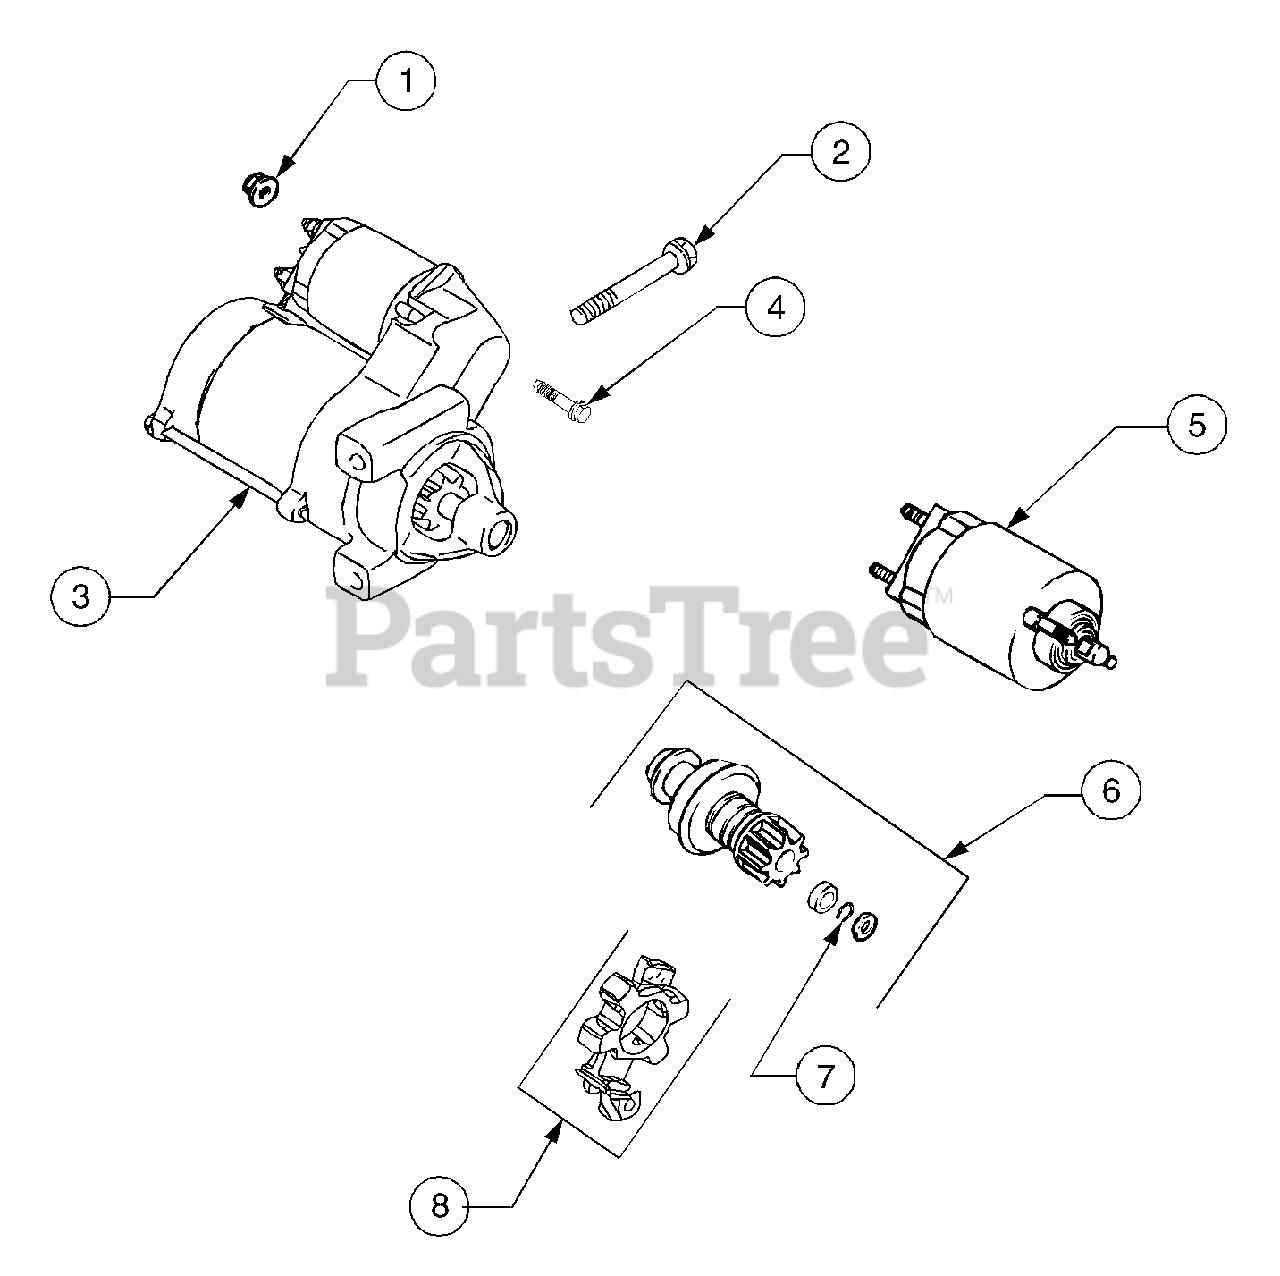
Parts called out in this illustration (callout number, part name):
1	Nut, Hex Flange M8 x 1.25"
2	Screw, Hex Flange M8 x 1.25 x 80
3	Starter, Solenoid Shift Assembly
4	Kit, Solenoid
5	Kit, Pinion Drive
7	Ring, Retainer
8	Screw, External Torx Hd.
